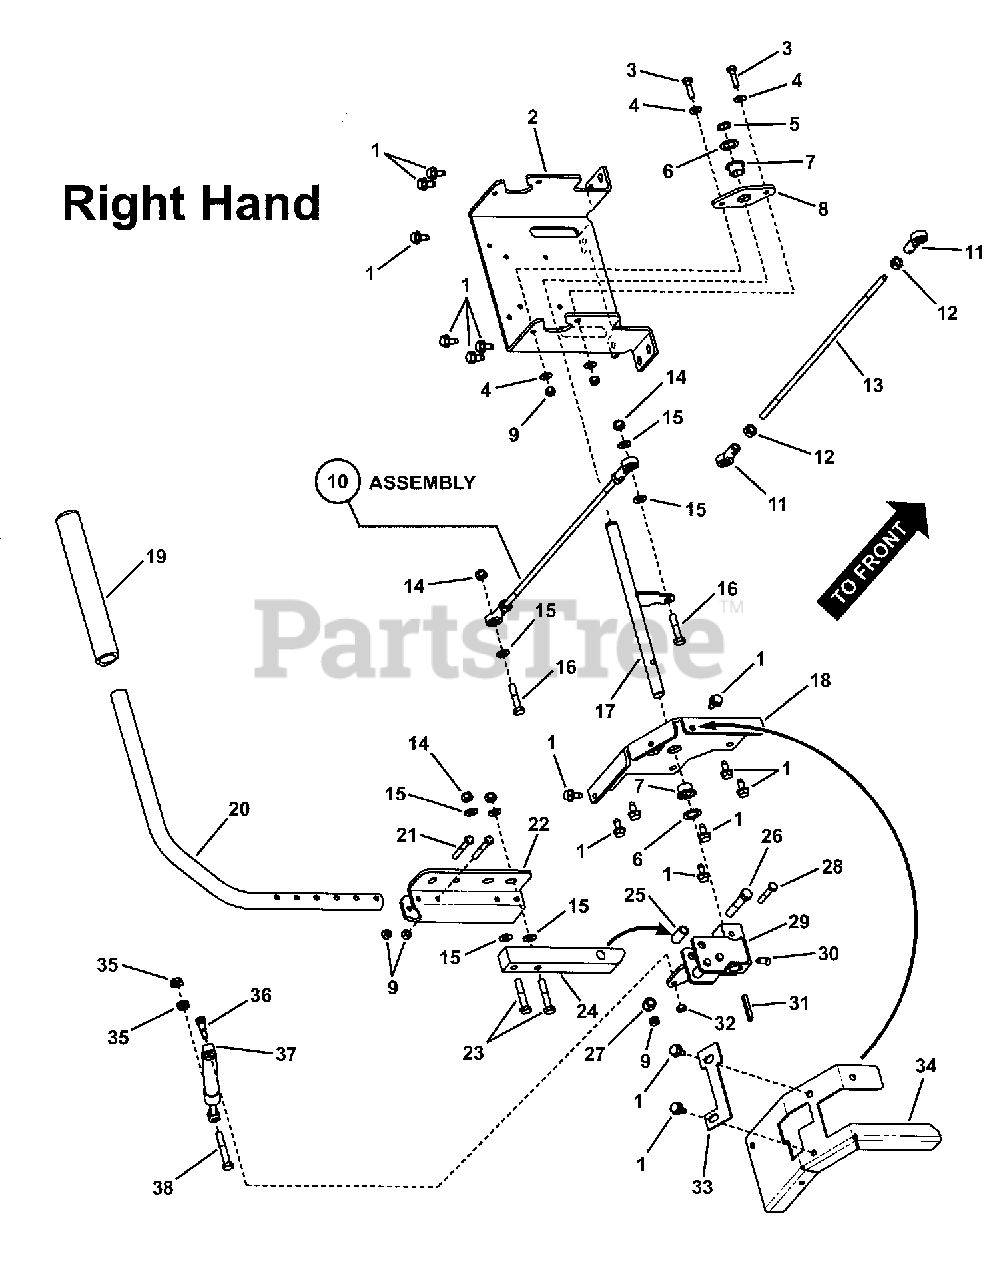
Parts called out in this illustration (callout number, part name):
1	SCREW, 5/16-18 x 5/8" Hex Washer Self-Tap
2	CHANNEL, Mounting
3	SCREW, 1/4-20 x 1" Hex Head Cap GR 5
4	WASHER, 1/4" Flat
5	RING, 5/8" External Retaining
6	WASHER, .64 I.D. x .99 O.D. x .05 Flat
7	BUSHING, Teflon Impregnated
8	MOUNTING PLATE, Left Hand Bearing
9	NUT, 1/4-20 HEX NYLON LOCK
11	ROD END (5/16-24 thread)
12	NUT, 5/16-24 Hex, GR 5 or B
13	LINKAGE ROD, Pump Control (5/16-24 thread)
14	NUT, 5/16-18 HEX NYLON LOCK
15	WASHER, 5/16" Flat
16	SCREW, 5/16-18 x 1-1/2" Hex Head Cap, GR 5
17	WELDMENT, Cross Rod
18	BUSHING MOUNT PLATE, Right Hand
19	GRIP, Twin Stick
20	HANDLEBAR, Twin Stick
21	SCREW, 1/4-20 x 1-3/4" Hex Head Cap, GR 5
22	BRACKET, Handle Adjustment
23	BOLT, 5/16-18 X 1-3/4 GD5 YZ
24	MOUNTING ARM
25	SPACER, .498 O.D. x 1.010" long
26	SCREW 3/8-16 x 2" Hex Head Cap, GR 5
27	NUT, 3/8-16 HEX NYLON LOCK
28	SCREW, 1/4-20 x 1-1/2" Hex Head Cap GR 5
29	WELDMENT, Mounting Hub, RH
30	SET SCREW, 5/16-18 x 1/2" Square Head Cup Point
31	KEY, 3/16" Square x 1-1/2"
32	NUT, 1/4-20 Hex Center Lock
33	PLATE, Speed Adjuster
34	PLATE, Bushing Mount, RH
35	NUT, 5/16-18 Hex Flange Lock
36	SCREW, 1/4-20 Shoulder Socket Head
37	DAMPENER, Hydraulic
38	BOLT, 5/16-18 X 2", GD5
